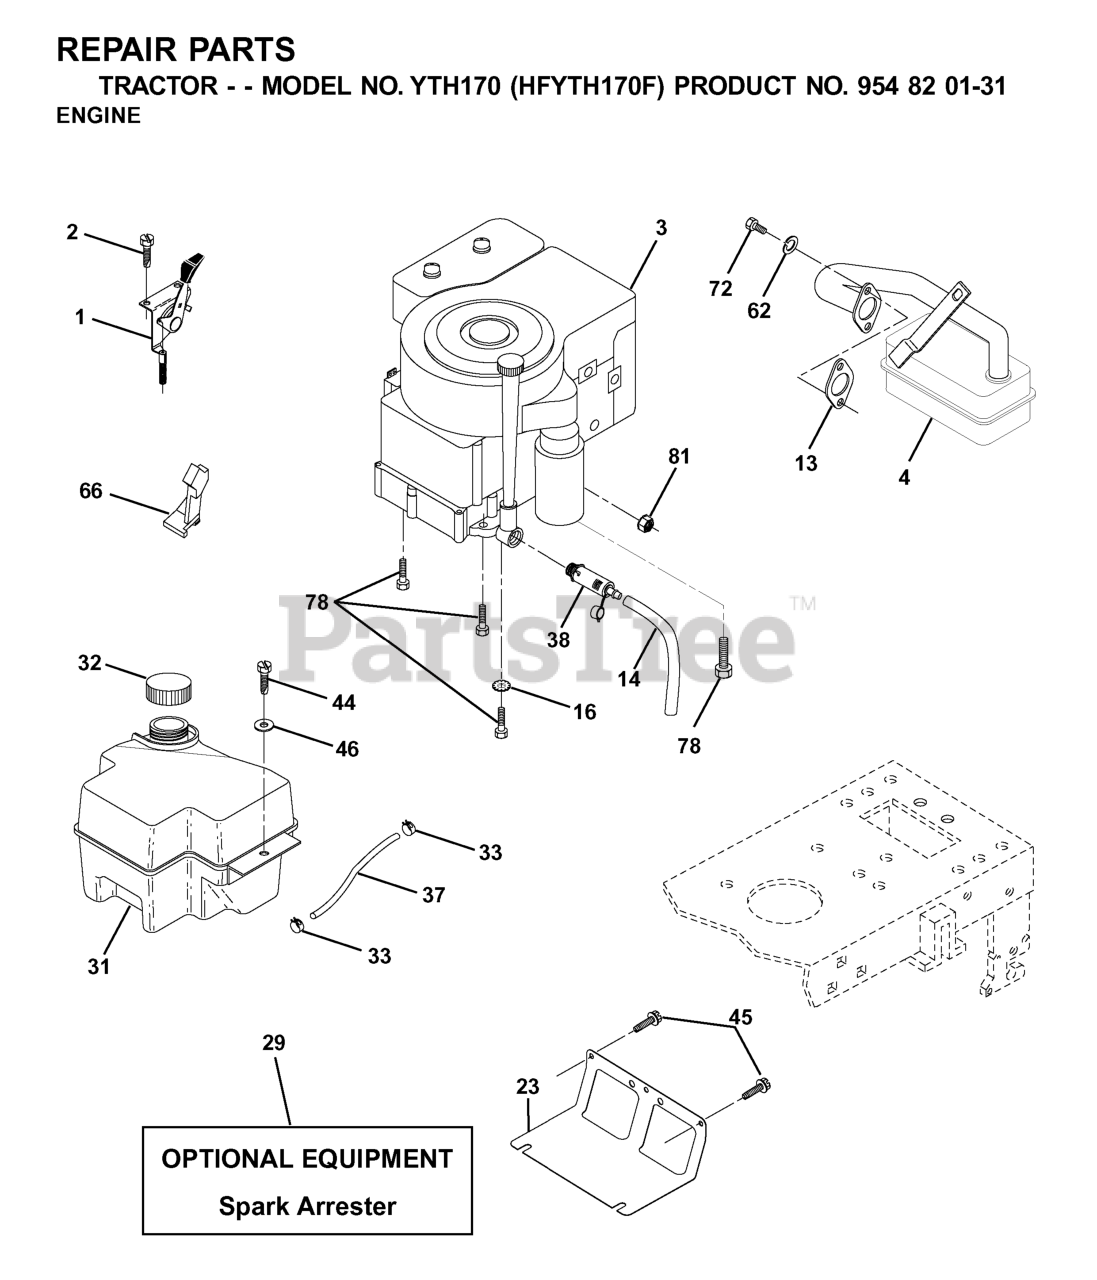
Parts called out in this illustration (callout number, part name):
1	THROTTLE.CONTROL.CABLE.BLACK
2	SCREW LT
4	MUFFLER.LT.BRIGGS.14HP.IC/OHV
13	REPL BY 532 27 22-93
14	TUBE, DRAIN OIL ASM.
16	LOCKWASHER
23	SHIELD.BROWNING.DBR.GUARD
29	KIT.SPARK ARRESTOR 794945 B&S
31	TANK, 2GAL
32	FUEL CAP
33	HOSE CLAMP
37	LINE.FUEL.20
38	PLUG, OIL DRAIN EASY
44	SCREW HEXWSHR 1/4-20X3/4
45	SCREW, 3/8-16X3/4
62	WASHER.LOCK.HVY.HLCL.SPR.5/16
66	STOP THROTTLE
72	SCREW
78	SCREW.3/8-16
81	NUT
